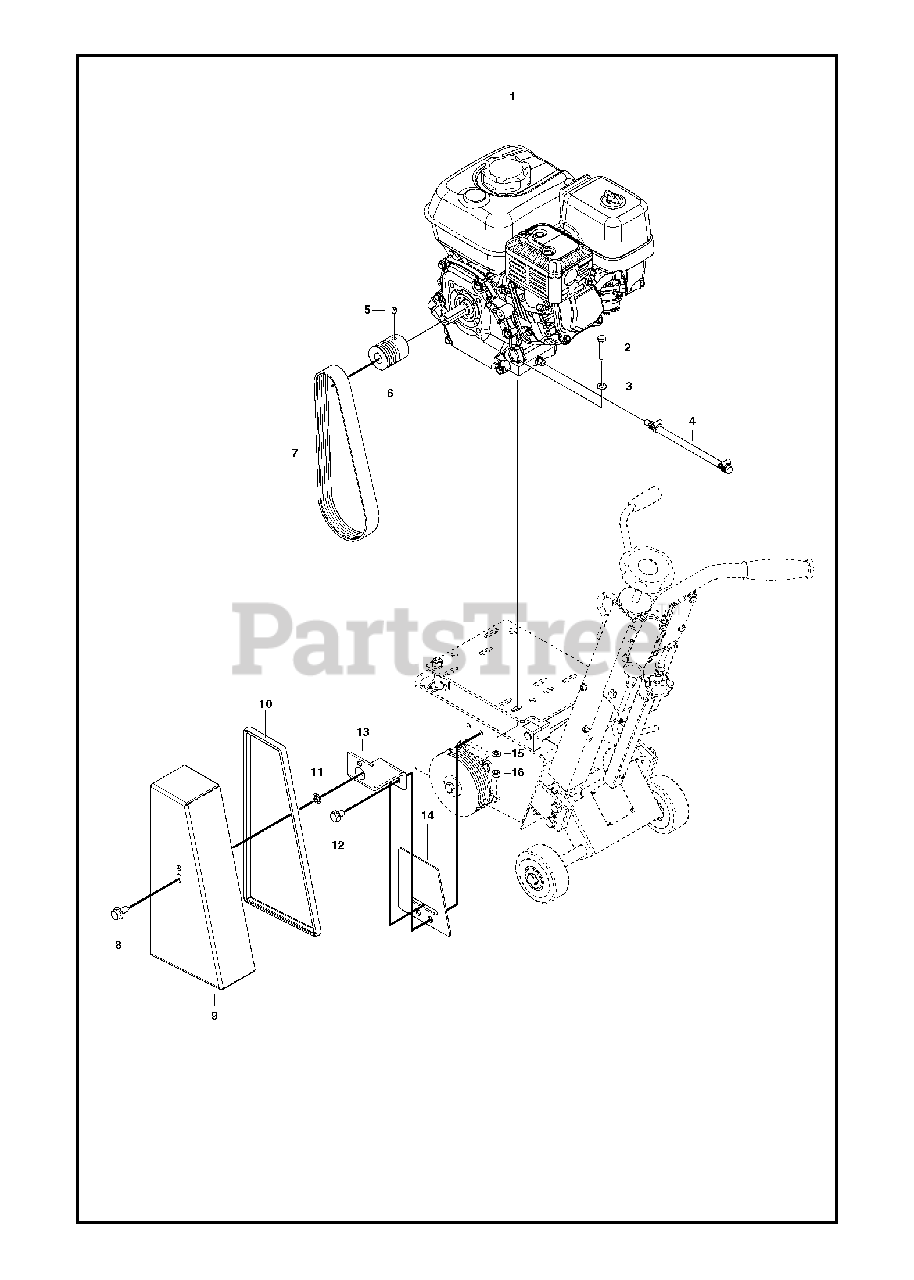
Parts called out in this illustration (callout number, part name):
3	WASHER
15	WASHER
16	HEXAGON NUT
